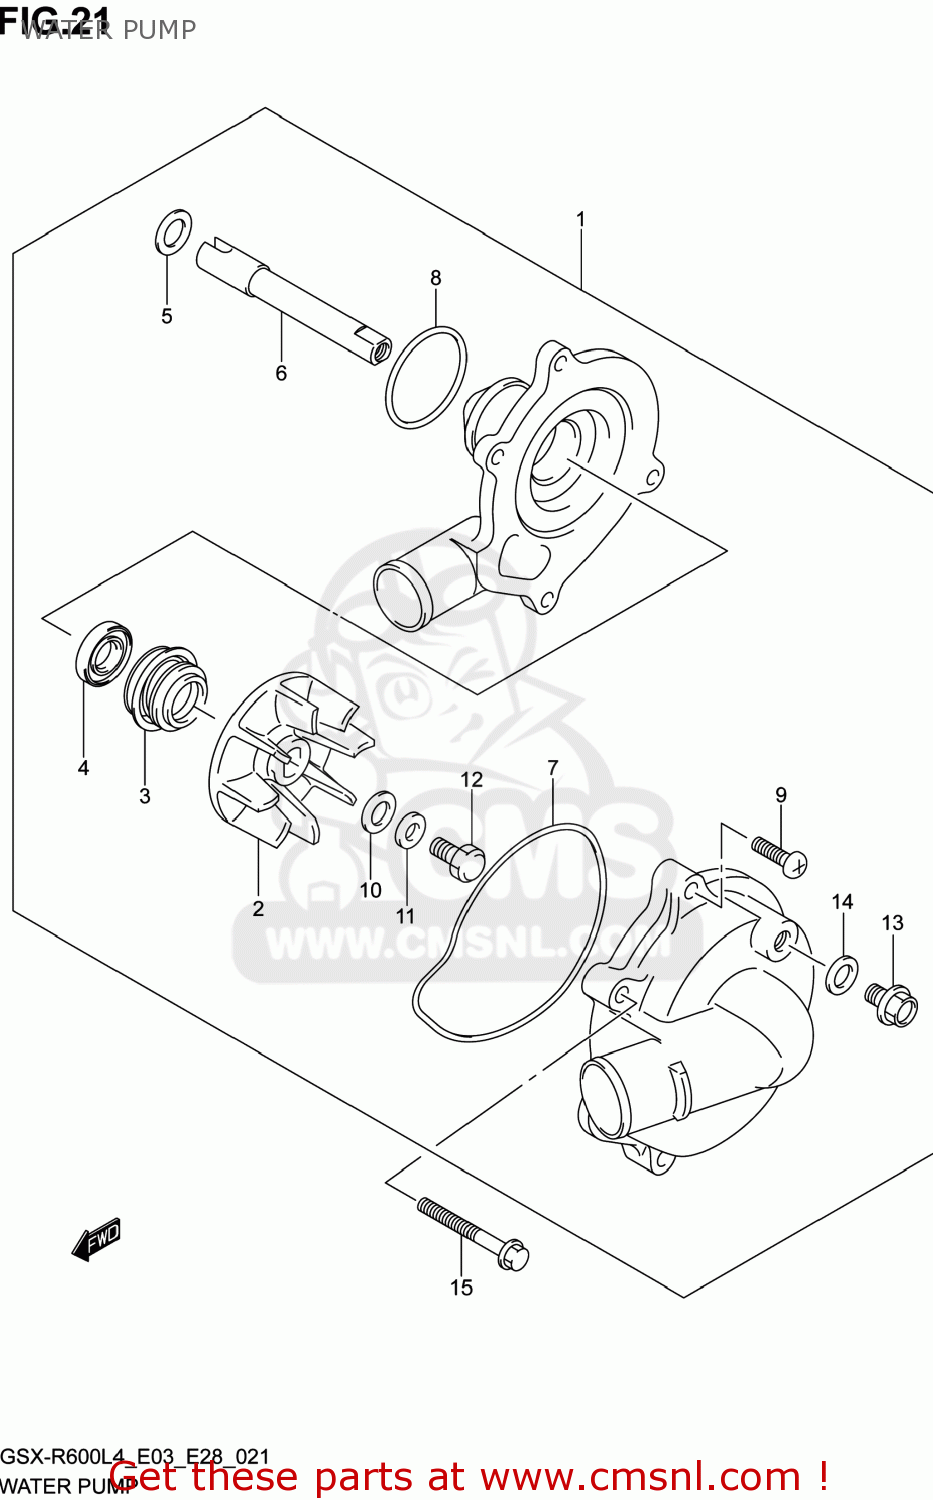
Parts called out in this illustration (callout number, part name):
1	PUMP ASSY,WATER
2	IMPELLER
3	SEAL,MECHANICAL
4	SEAL,OIL
5	WASHER
6	SHAFT
7	O RING
8	O RING,WATER PUMP HOLDER
9	SCREW
10	GASKET(6X15X2.2) (NAS)
11	WASHER
12	BOLT(6X13)
13	BOLT,DRAIN
14	GASKET(8.2X14X1) (NAS)
15	BOLT
